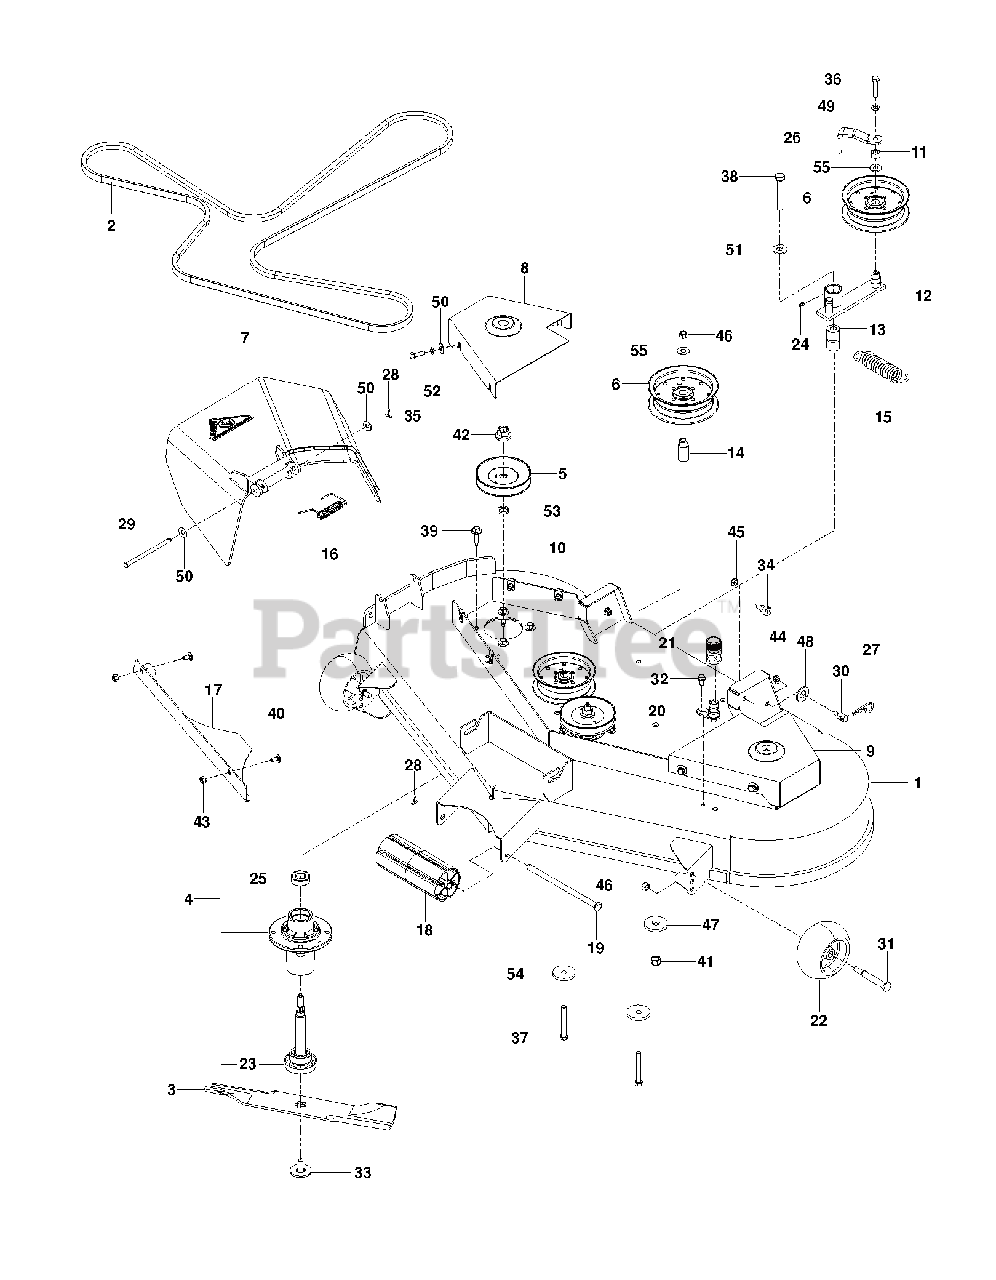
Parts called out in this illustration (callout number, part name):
1	DECK.48".TRI-FORCE.W/DECALS.OR
2	BELT, DECK
3	BLADE, 16-1/4"
4	MANDREL.DECK.ASSEMBLY
5	MANDREL PULLEY
6	PULLEY, IDLER
7	DISCHARGE CHUTE 48"
8	BELT SHIELD - R.H. ORANGE
9	BELT SHIELD - L.H. ORANGE
10	U-CLIP 5/16-18 NUT RETAINER
13	PIVOT BUSHING
14	IDLER BUSHING
16	SPRING - TORSION
17	CONFINEMENT PLATE 48" BLK
18	NOSE ROLLER 48"
19	ROD.ROLLER.NOSE.NARROW.48"
20	PORT.WASHOUT
21	COUPLING.QUICK CONNECT
22	GAUGE WHEEL
23	GREASABLE MANDREL SHAFT
24	ZERK
25	BEARING, BALL
26	GUIDE, BELT
27	HAIRPIN #4
28	RP_COTTER PIN 1/8 X 3/4
29	PIN-CLEVIS 5/16 DIA X 5.19 ZD
30	STUD.FASTNER.W/ANTI-ROTATE
31	SHOULDER BOLT 1/2X2-5/8 ZD SPE
32	BOLT 1/4-20 X 1/2 HWST
33	BOLT.WASHER.ASM.7/16-2
34	SB 3/8-16 X 3/8 SKT HD ZD
35	HCS 5/16C X 1
36	HCS 3/8-16 X 1 3/4 GR5
37	HCS 3/8C X 3
38	HCS 1/2C X 3 1/4
39	WASHER HEAD SCREW
40	CARRIAGE BOLT 5/16C X 5/8"
41	RP NUT 1/2-13 HEX NYLOC ZD
42	LOCKNUT - 9/16
43	NUT 5/16 NYLOC
44	5/16-18 NYLOC FLANGE NUT
45	NUT HEX 3/8-16 NYLON, THIN
46	NUT 3/8-16 NYLOC
47	WASHER, SUPPORT
48	WASHER 5/8 FLAT
49	SLW 3/8 STD
50	WASHER 5/16 FLAT
51	WASHER 1/2 FLAT
52	WASHER 5/16 LOCK
53	WASHER-SPACER
54	SPINDLE WASHER
55	RP WASHER 3/8 FLAT
